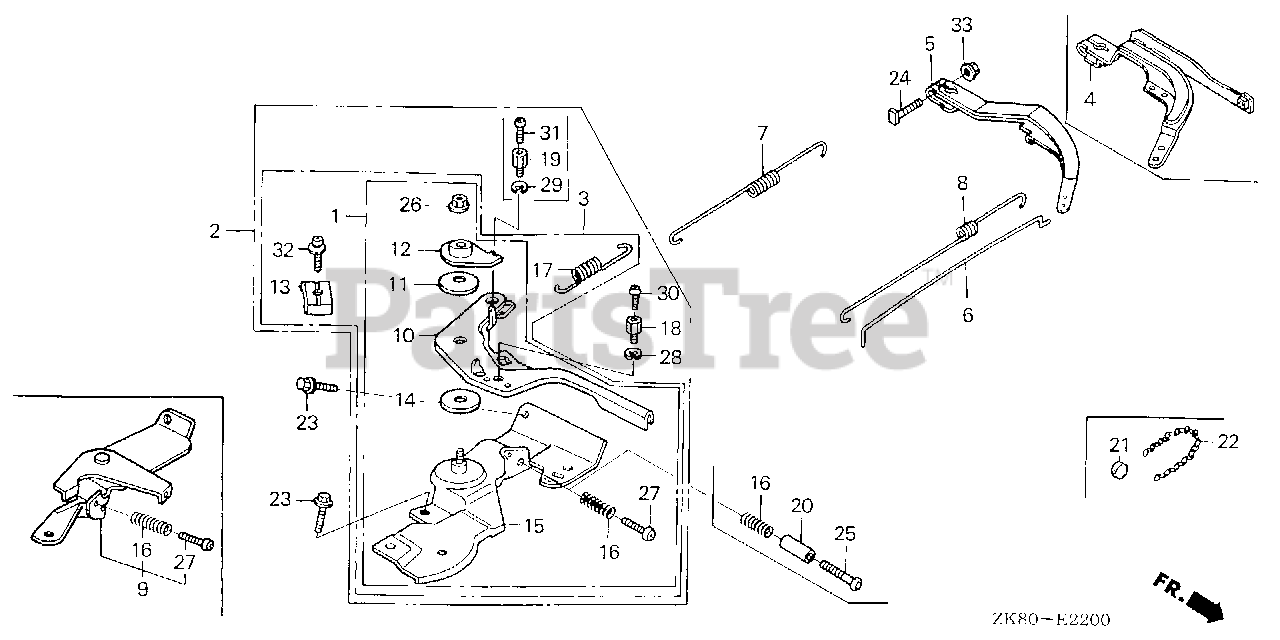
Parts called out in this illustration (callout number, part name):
3	CONTROL ASSY. (REMOTE)
5	ARM, GOVERNOR
6	ROD, GOVERNOR
7	SPRING, GOVERNOR
8	SPRING, THROTTLE RETURN
10	LEVER, CONTROL
11	SPRING, LEVER
12	WASHER, CONTROL LEVER
13	HOLDER, CABLE
14	SPACER, CONTROL LEVER
15	BASE, CONTROL (REMOTE)
16	SPRING, CONTROL ADJUSTING
17	SPRING, CABLE RETURN
23	BOLT, FLANGE (6X12) (CT200)
24	BOLT, GOVERNOR ARM
26	NUT, SELF-LOCK (6MM)
27	SCREW, PAN (5X25)
32	SCREW, PAN (5X16)
33	NUT, FLANGE (6MM)
